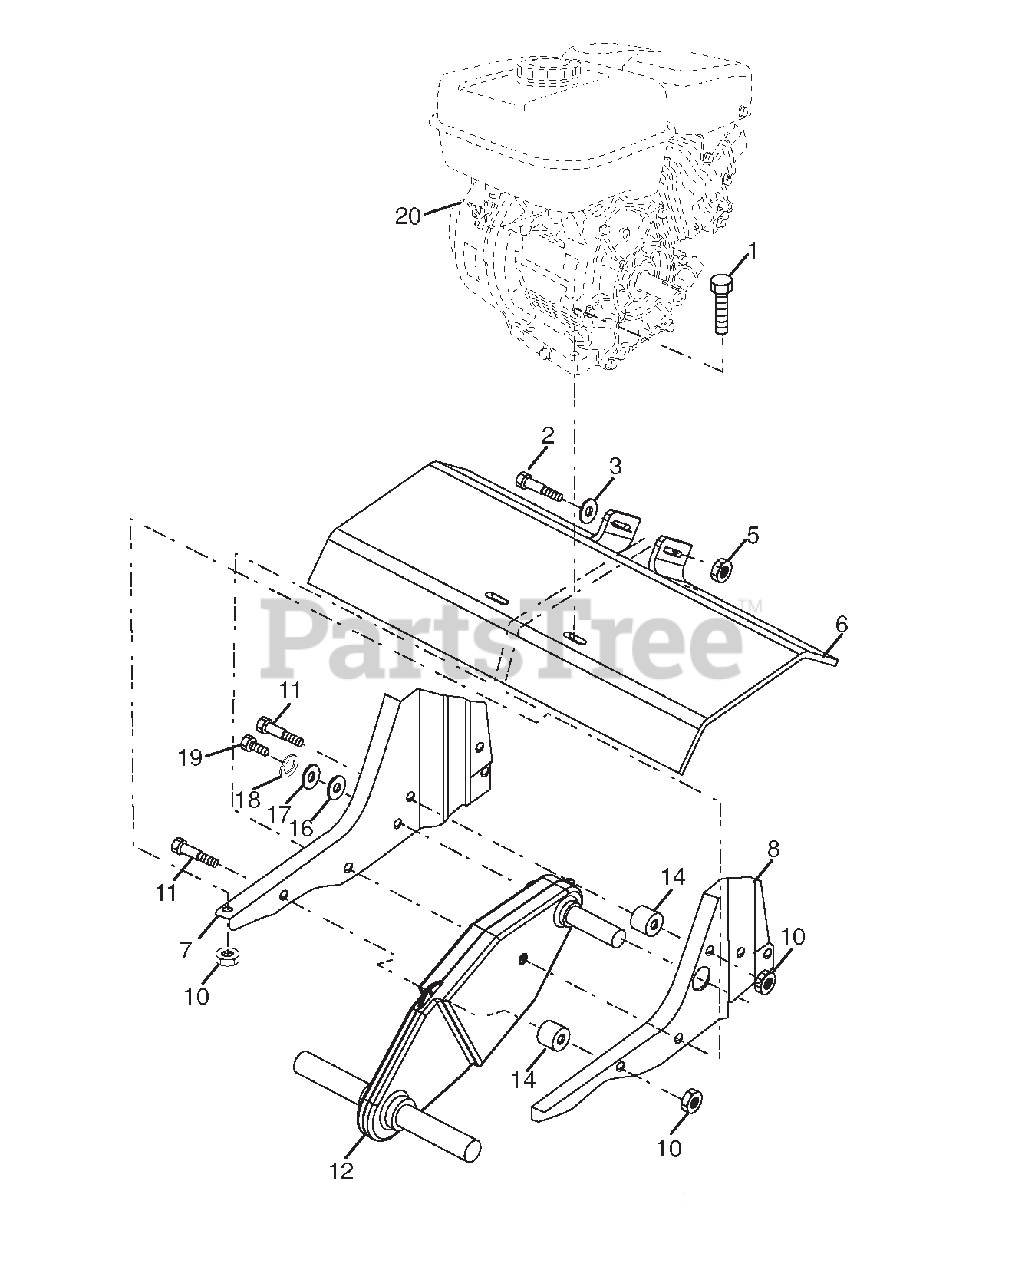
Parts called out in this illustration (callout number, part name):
1	Bolt, Hex Head, Gr. 25/16-18 x
2	Bolt, Hex Head, 3/8-16 x 3-1/4
3	Washer 13/32 x 13/16 x 11 Ga.
5	Nut, Hex, Flangelock 3/8-16
6	SHIELD, TINE
7	Bracket, Engine, R.H.
8	Bracket, Engine, L.H.
10	Nut, Hex, Flangelock
11	Bolt, Shoulder
12	Transmission
14	Spacer, Split
16	Washer, 9/32 x 7/8 x 12 Ga.
17	Washer, 9/32 x 1-1/4 x 16 Ga.
18	Washer, Lock 1/4
19	Bolt, Hex Head, Gr. 51/4-28 x
20	Engine, Subaru, Model Number EX170DT1030 (Order parts from engine manufacturer)
